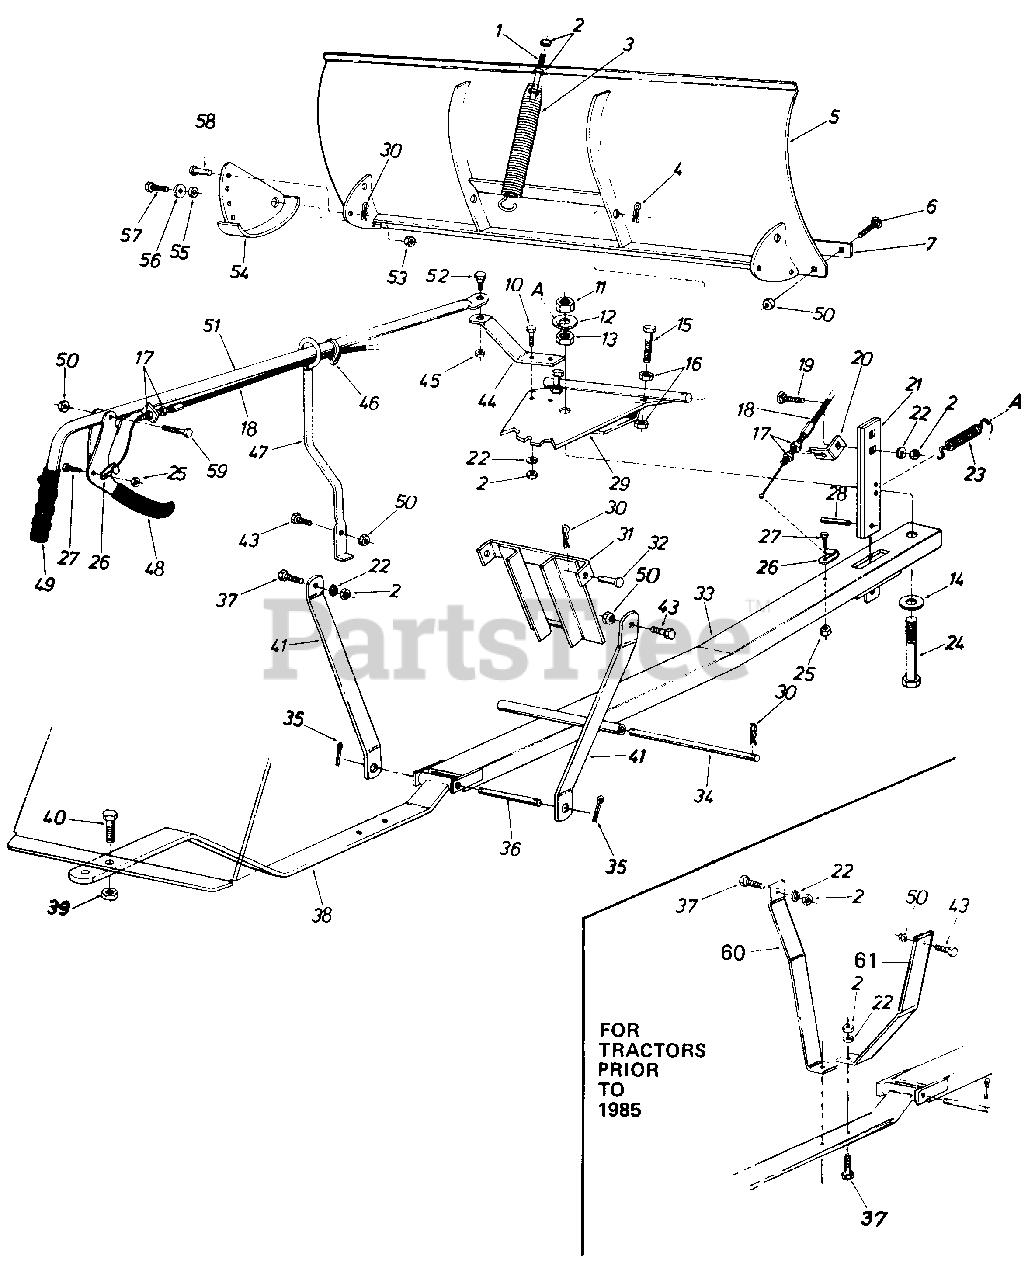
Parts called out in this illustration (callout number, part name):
1	Hex Scr. 3/8-16 x 4.50" Lg.*
2	Hex Nut 3/8-16 Thd.'
3	Blade Adjustment Spring
4	Hair Pin Cotter 5/32" Dia.
5	48" Blade Ass'y.
6	Carriage Bolt 5/16-18 x.75" Lg.*
7	Wear Plate 48"
10	Hex Scr. 3/8-16 x 1.00" Lg.*
11	Hex L.-Nut 3/4-10 Thd.
12	Fl.-Wash..810" I.D. x 2.00" O.D.
13	Hex Jam Nut 3/4-10 Thd.*
14	Fl.-Wash..810" I.D. x 2.00" O.D.
15	Hex Scr. 1/2-13 x 2.00" Lg.*
16	Hex Nut 1/2-13 Thd.*
17	Hex Jam Nut 5/16-24 Thd.*
18	Control Cable Ass'y.
19	Carriage Bolt 3/8-16 0 x 1.25" Lg.*
20	Cable Guide Bracket
21	Angle-Lock Bar
22	L.-Wash. 3/8" Scr.*
23	Angle Lock Spring
24	Hex Scr. 3/4-10 x 4.00" Lg.
25	Hex L.-Nut 1 /4-20 Thd.
26	Clevis Lanyard F itting
27	Hex Scr. 1/4-20 x .75" Lg. *
28	Spring Pin Spirol 1/4" Dia. x 1.00" Lg.
29	Pivot Plate Ass y.
30	Hair Pin Cotter 3/32" Dia.
31	Guide Bracket Ass'y.
32	ClevisPin 1/2" Dia. x 1.00" Lg.
33	Push Bar Ass'y.
35	Cotter Pin 5/32" Dia. x 1.00" Lg.*
37	Hex Scr. 3/8-16 x 1.25" Lg.
38	Hanger Bracket Ass'y.
39	Hex L. Nut 5/8-11 Thd.
40	Hex Scr. 5/8-11 x 1.50" Lg.*
41	Hanger Link
43	Hex 5/16-18 x 1.00" Lg. *
44	Blade Pivot Bracket
45	Hex Jam Nut 3/8- 16 Thd.
46	Nylon CableTie
47	Tube Guide Ass'y.
48	Clutch Grip Ass'y.
49	Grip-3/4" Handle
50	Hex L-Nut 5/16-18 Thd.
51	Tube Handle Ass'y.
52	Shld. Scr.-Special 3/8-16 Thd.
53	Hex L.-Nut 3/8-16 Thd.
54	Skid Assembly
55	Spacer
56	Fl.-Wash..385" I.D. x 1.00" O.D.
57	Hex Scr. 3/8-16 x .75" Lg.*
58	ClevisPin5/16" Dia. x.75" Lg.
59	Hex Scr. 5/16-18 x 1.50" Lg.
60	Mounting Brkt.-L.H.
61	Mounting Brkt.-R.H.
